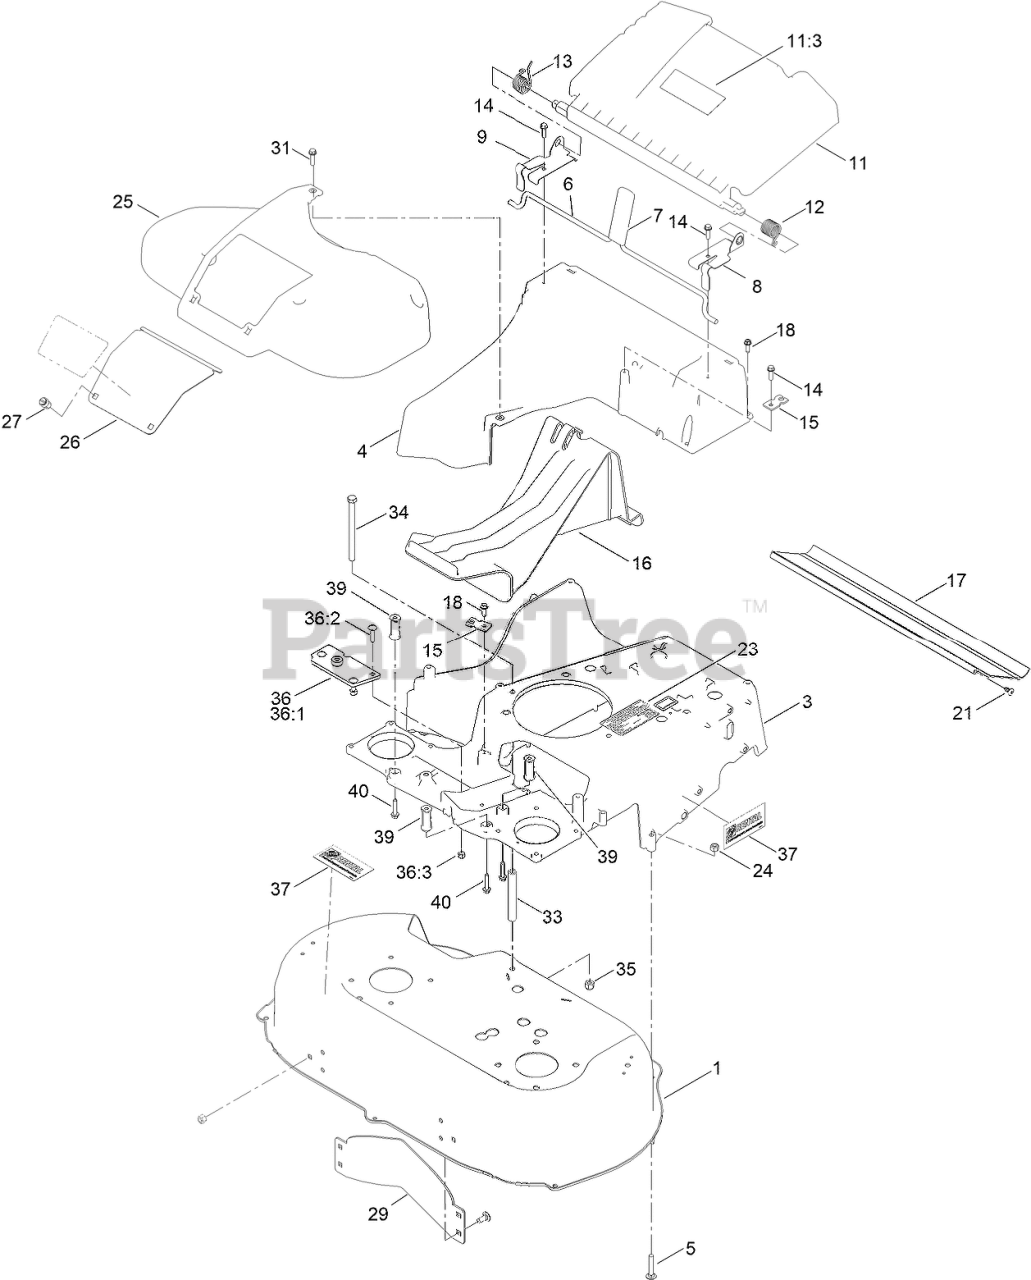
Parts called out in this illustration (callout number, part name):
1	HOUSING ASM
3	FRAME-30"
5	BOLT-CAR
6	ROD-RELEASE, HANDLE
7	GRIP-LEVER
8	BRACKET-DOOR, LH
9	BRACKET-DOOR, RH
11	REAR DEFLECTOR ASM
11:3	DECAL-WARNING
12	SPRING-TORSION
13	SPRING-TORSION
14	SCREW-HWH
15	BRACKET-CABLE, TRACTION
16	PLUG-MULCH
17	SHIELD-TRAILING
18	SCREW-HWHTF
21	SCREW-PTH
23	DECAL-ARRESTOR, SPARK
24	NUT-LOCK, NI
25	COVER-BELT
26	DOOR-ACCESS
27	FASTENER
29	BAFFLE-CONTROL
31	SCREW-HWHTF
33	SPACER-SHIELD
34	SCREW-HH
35	NUT-HEX
36	FRAME PLATE KIT
36:1	PLATE-FRAME
36:2	SCREW-CARR
36:3	NUT-LOCK, NI
37	DECAL-TOOL, THD
39	SPACER-FRAME, 30 IN.
40	SCREW-HWHTF
